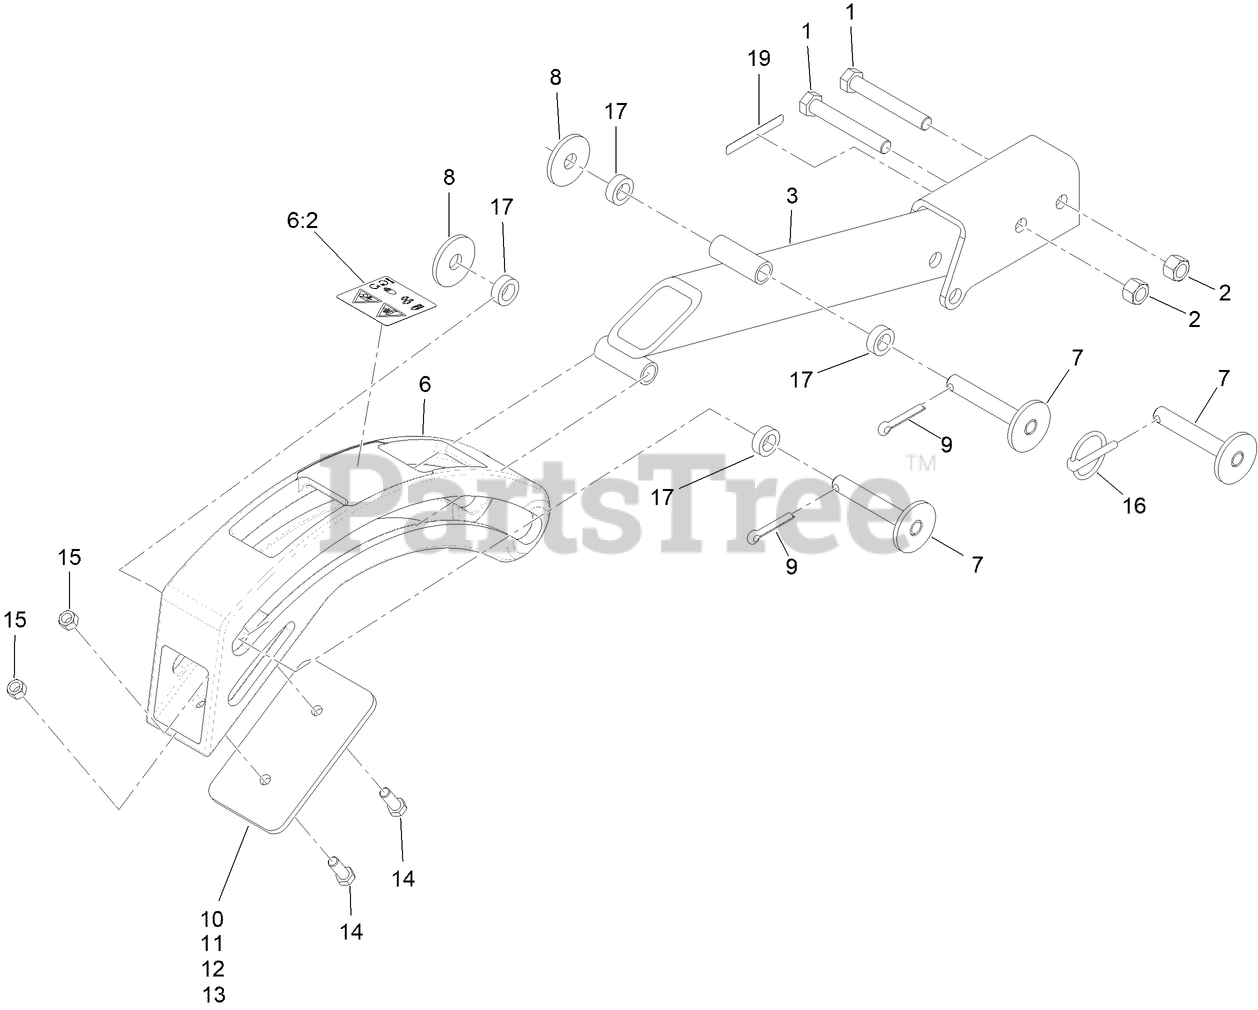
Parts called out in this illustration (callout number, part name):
1	SCREW-HH
2	NUT-HEX
3	CRUMBER SUPPORT ASM
6	CRUMBER SLIDE ASM
6:2	DECAL-WARNING, CRUMBER
8	WASHER
9	PIN-COTTER
10	PLATE-DEFLECTOR, 4 INCH
11	PLATE-DEFLECTOR, 6 INCH
12	PLATE-DEFLECTOR, 8 INCH
13	PLATE-DEFLECTOR, 12 INCH
14	SCREW-HH
16	KLIK PIN ASM
17	BUSHING
19	DECAL-WARNING
